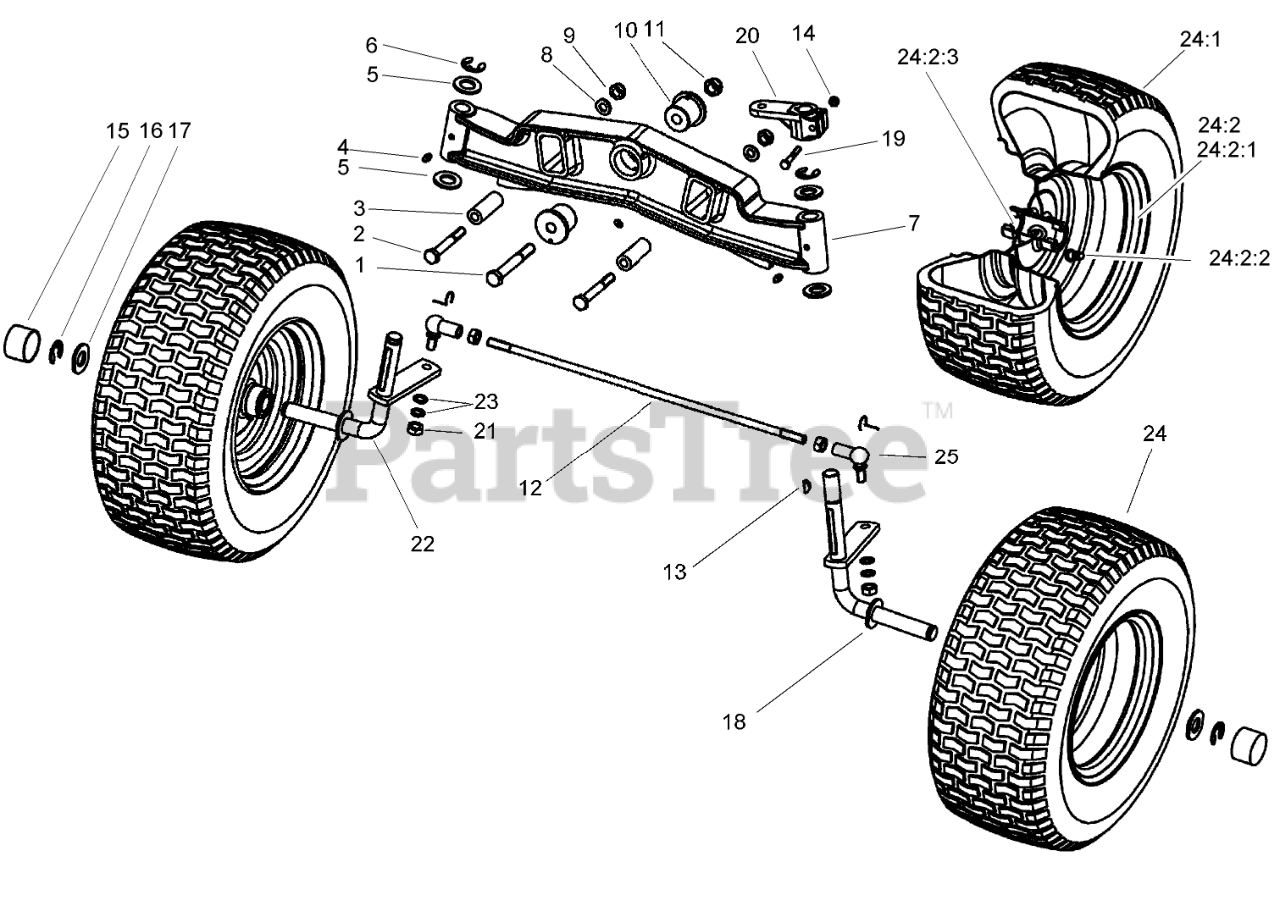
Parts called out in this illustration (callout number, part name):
1	SCREW-HH
2	SCREW-HH
3	SPACER
4	FITTING-GREASE
5	WASHER-FLAT
6	CLIP-SPRING
7	AXLE-FRONT
8	WASHER-FLAT
9	NUT-LOCK, NI
10	BUSHING-AXLE, FRONT
11	NUT-LOCKING, SELF
12	ROD-TIE, FRONT AXLE
13	KEY-WOODRUFF
14	NUT-LOCK
15	CAP-HUB
16	CLIP-SPRING
17	WASHER
18	SPINDLE-LH
19	SCREW-HH
20	LEVER-SPINDLE, STEERING
21	NUT-HEX
22	SPINDLE-RH
23	Washer
24	TIRE and WHEEL ASM
24:2	WHEEL ASM
24:2:1	RIM
24:2:2	Valve-Tire
24:2:3	BEARING-WHEEL
25	JOINT-BALL, ANGLE
